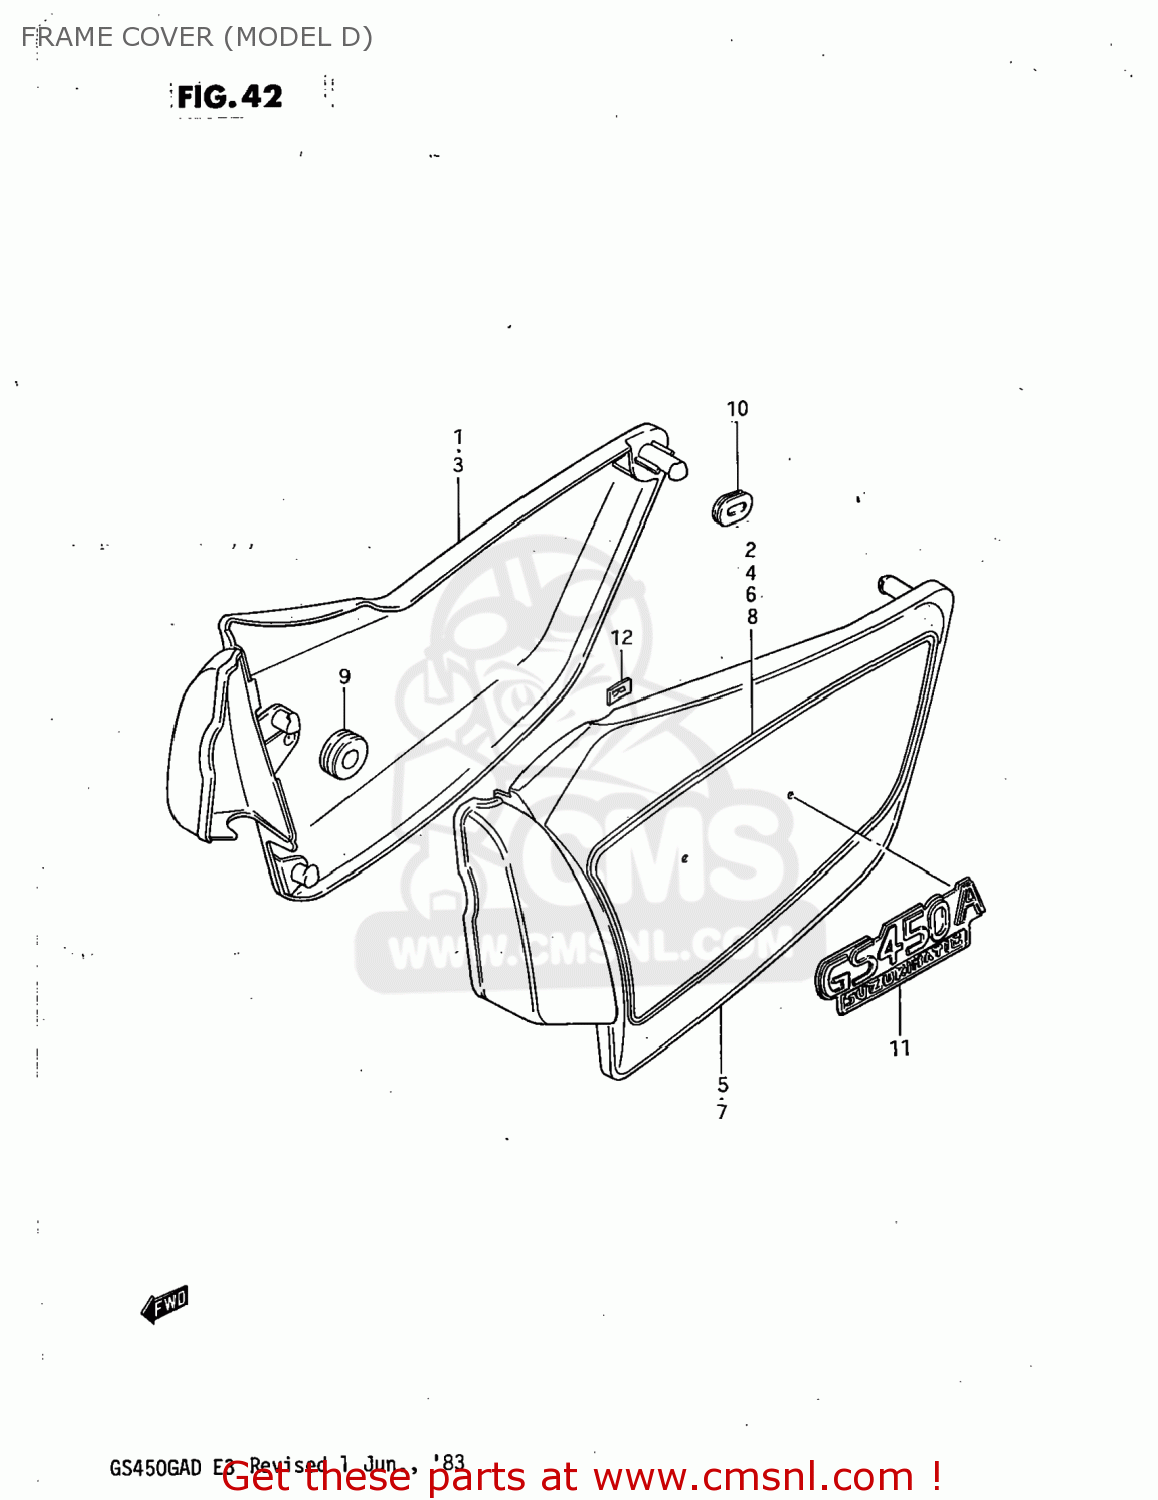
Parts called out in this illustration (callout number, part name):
1	COVER,FRAME,RIGHT
2	TAPE SET,FRAME COVER
3	COVER,FRAME,RIGHT
4	TAPE SET,FRAME COVER,RIGHT
5	COVER,FRAME,LEFT
6	TAPE SET,FRAME COVER
7	COVER,FRAME,LEFT
8	TAPE SET,FRAME COVER
9	CUSHION
10	CUSHION
11	EMBLEM,FRAME COVER
12	NUT
